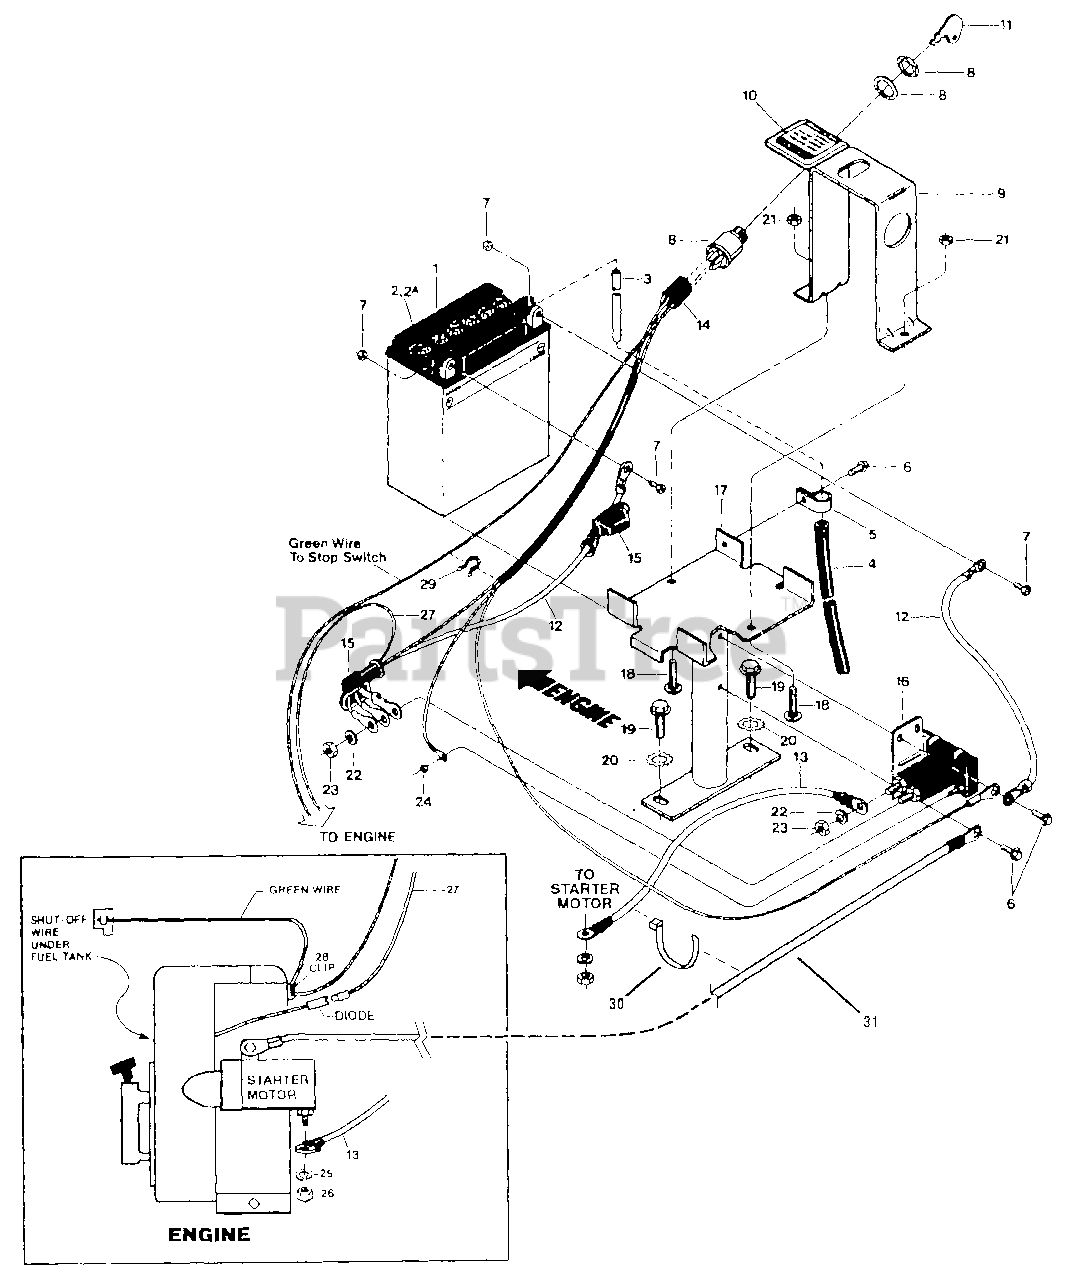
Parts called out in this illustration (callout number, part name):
1	Battery-12 volt, 9 ampere
2	Cap-battery, yellow replacement cap
2A	Cap-battery, white replacement cap
3	Vent Tube-battery
4	Shield-vent tube (hard plastic)
5	Clamp-vent tube shield
6	Screw-flanged hex hd., self-threading, 1/4-20 x 1/2
7	Battery Hdwr Kit
8	Switch, Ignition
9	Battery Hold-Down Clamp
10	Decal-ignition switch instructions
11	Key-ignition, one pair
12	Cable-battery
13	Cable-solenoid to starter motor
14	Wire Harness & Connecting Terminal Assy
15	Boot-terminal insulating
16	Solenoid
17	Bracket-battery
18	Screw-round hd., square neck, 1/4-20 x 1-1/4
19	Screw-flanged hex hd., 5/16-18 x 1
20	Lockwasher, external tooth
21	Locknut-hex, 1/4-20
22	Lockwasher-5/16
23	Nut-hex, 5/16-24
24	Locknut-hex, #10-32
27	Wire Assembly-recharging
28	Clip-holds recharging line
29	Tie - plastic, wire retaining
30	Tie - plastic, wire retaining
31	Cable - ground wire to starter motor bracket
